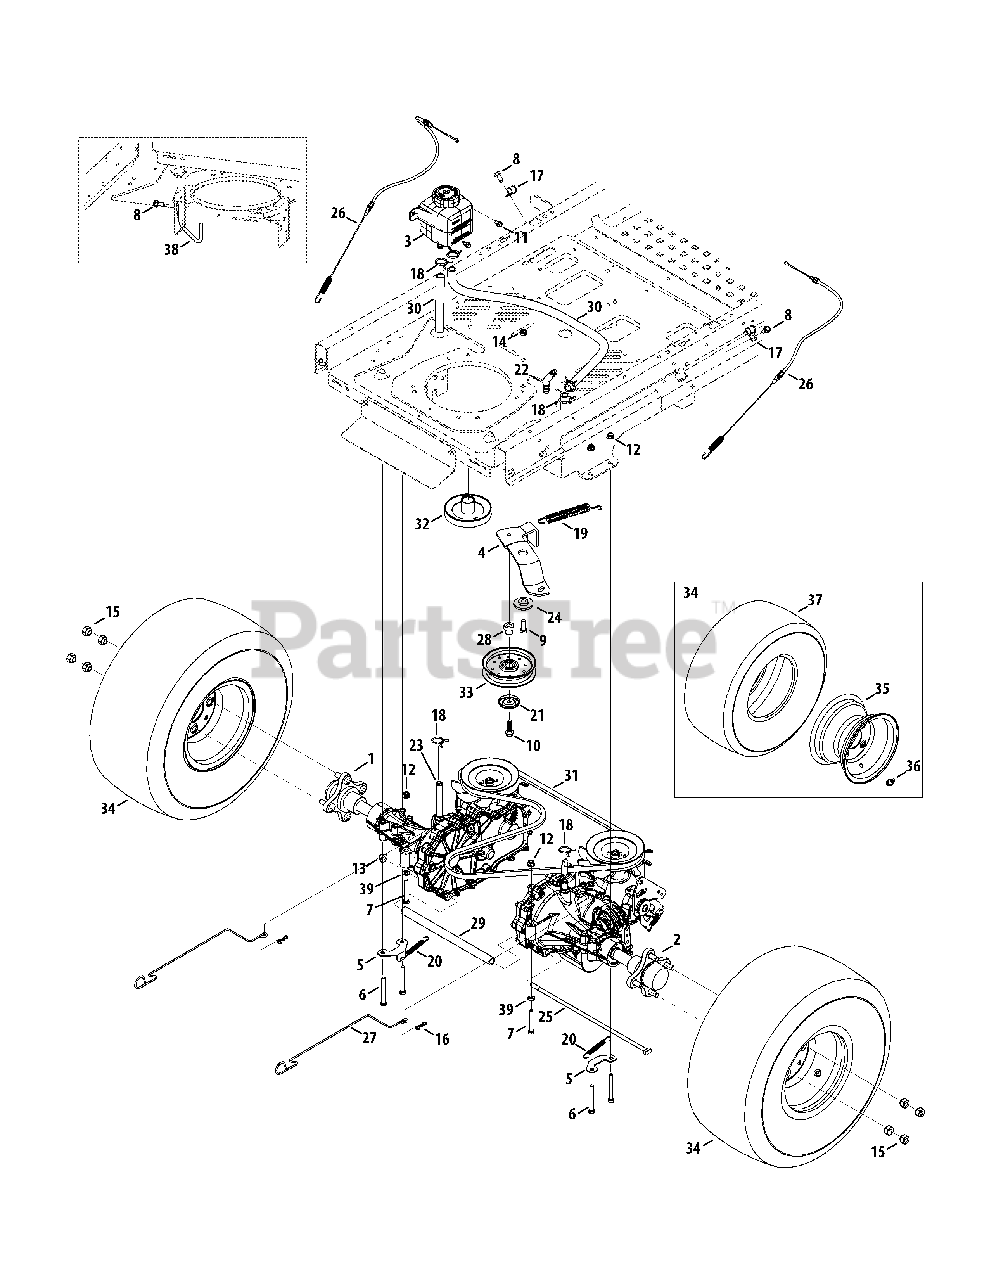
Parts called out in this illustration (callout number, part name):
1	Transmission Assembly, LH
2	Transmission Assembly, RH
3	Expansion Tank Assembly
4	Idler Bracket
5	Brake Mounting Bracket
6	Hex Screw, 5/16-18 x 2.75
7	Hex Cap Screw, 5/16-18 x 2.25
8	Hex Washer Screw, 5/16-18 x .750
9	Hex Screw, 3/8-16 x 1.00
10	Hex Washer Screw, 3/8-16 x 1.250
11	Hex Washer Screw, 1/4-20 x .625
12	Flange Lock Nut, 5/16-18
13	Flange Lock Nut, 3/8-16
14	Jam Lock Nut, 3/8-16
15	Lug Nut, 7/16-14
16	Bow-Tie Cotter Pin
17	Clamp 9/16 Dia.
18	Hose Clamp, .75 Dia. x .312
19	Extension Spring, .75 Dia. x 6.02
20	Extension Spring, .38 OD x 3.25 LG
21	Pulley Cap
23	Fitting, 9/16, Barb
24	Shoulder Spacer, .884 x .190
25	Rod, .337 Dia. x 14.75 LG
26	Park Brake Cable
27	Bypass Rod
28	Shoulder Spacer
29	Spacer, .75 OD x 11.31 LG
30	Fuel Hose, 1/2 ID
31	Belt, A-Type x 67.0
32	Engine Pulley
33	Idler Pulley, 4.25 Dia.
34	Complete Wheel, 20 x 10-8
36	Valve Tubeless
38	Engine Keeper Rod
39	Flat Washer .330 ID x .630 OD
